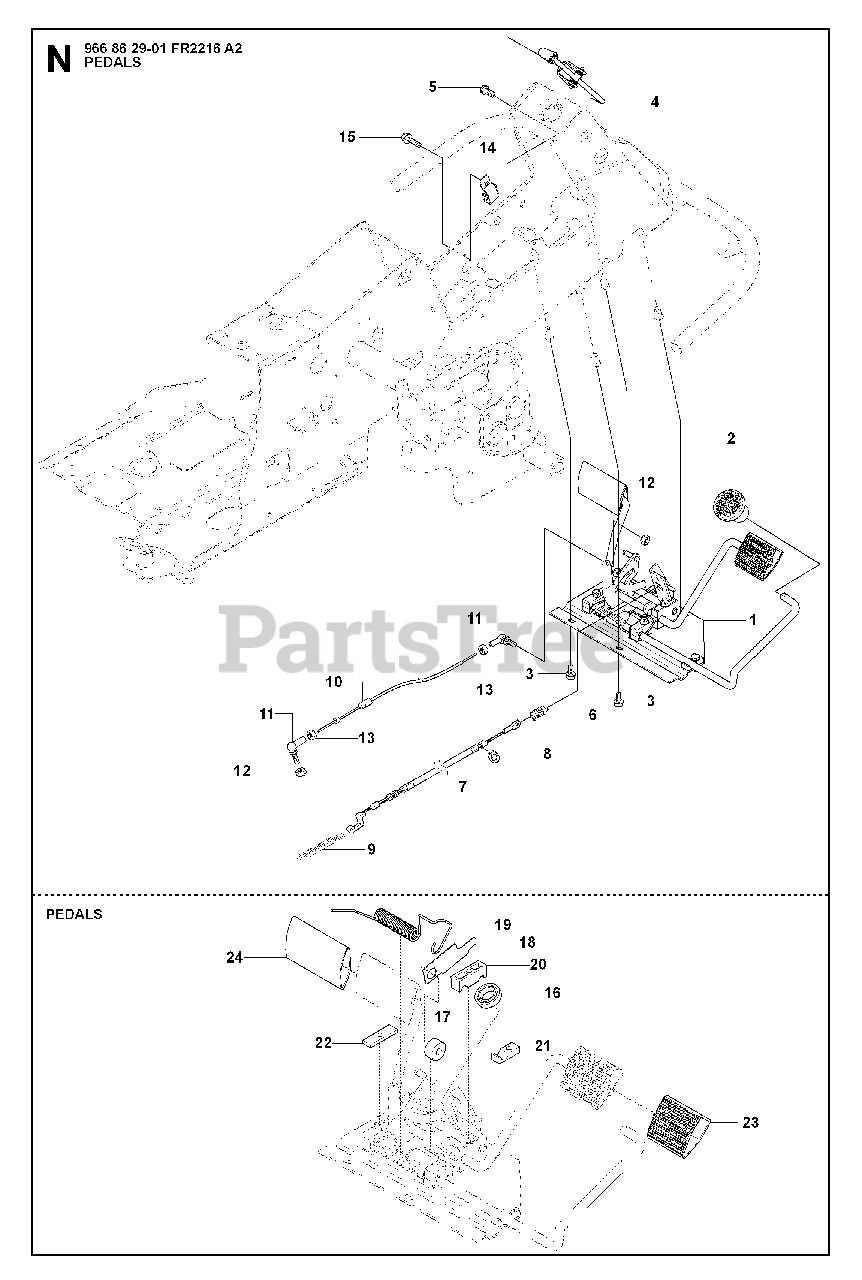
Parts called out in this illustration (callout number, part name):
1	PEDAL ASSEMBLY
2	KNOB
4	BRAKE LEVER ASSY
7	BRAKE WIRE
10	%WIRE
11	CONNECTOR
12	LOCKNUT M5
14	BRACKET
16	BALL BEARING 6002-2RS1
17	ROLLER
18	PLATE
19	SPRING
20	PEDAL SHAFT CLAMP
21	SUPPORT
22	PLATE
23	PEDAL RUBBER
24	PEDAL RUBBER, SF
